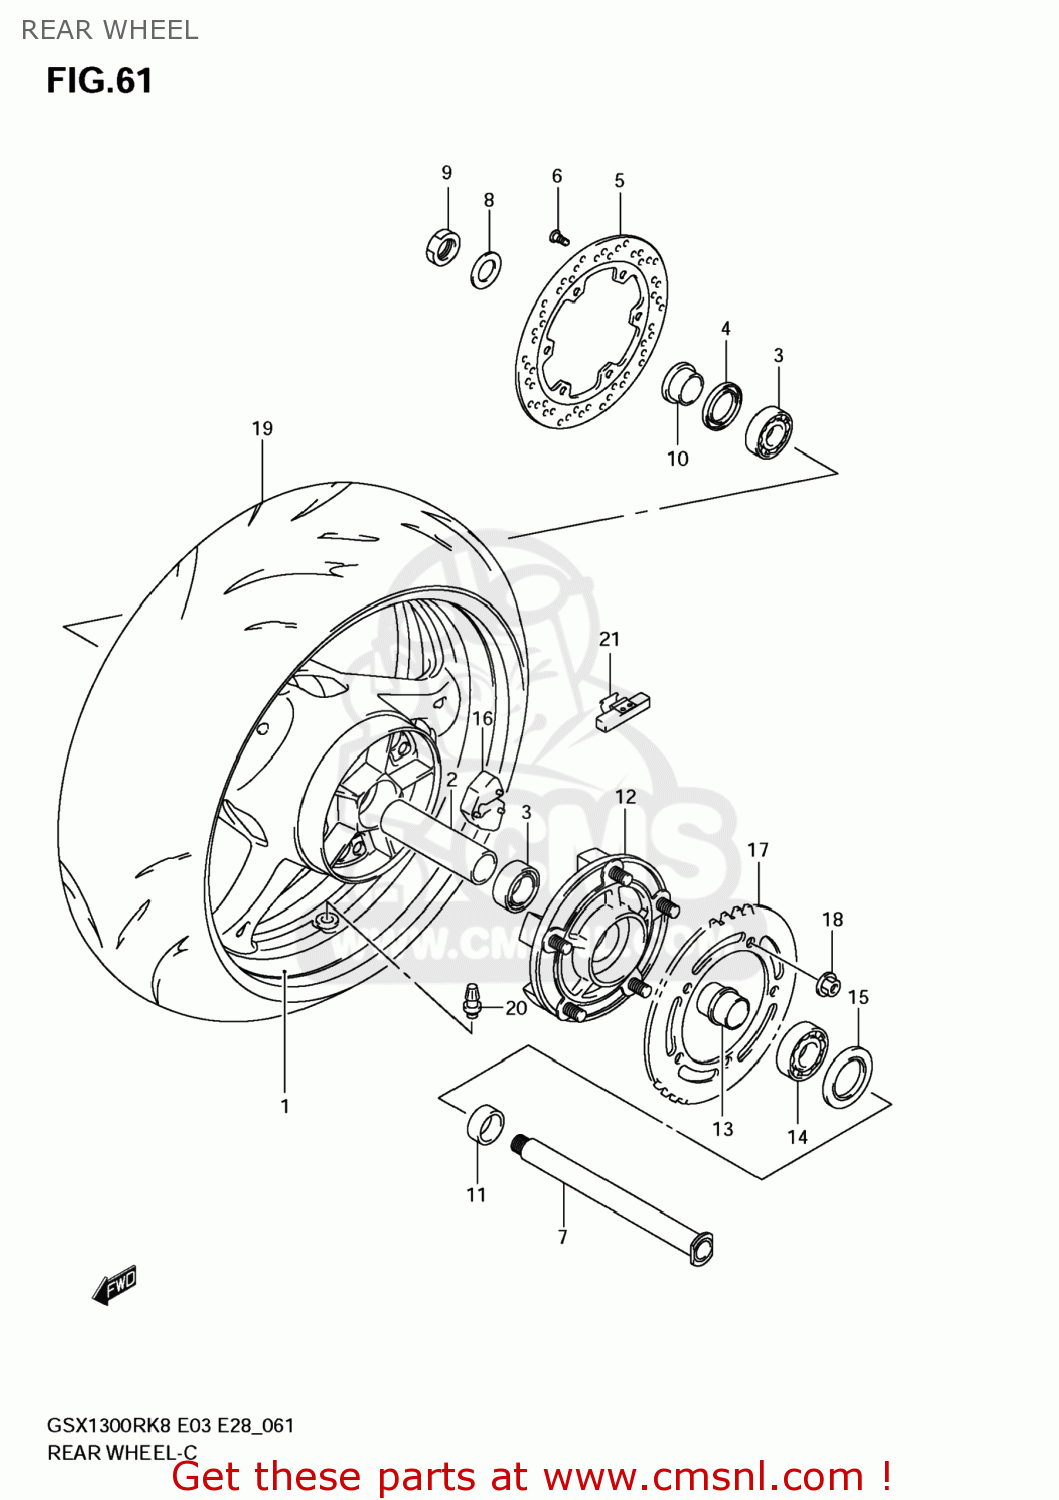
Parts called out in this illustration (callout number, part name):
1	WHEEL,RR(17M/CXMT6.00)
2	SPACER,RR WHEEL BEARING
3	BEARING(28X52X12)
4	SEAL,OIL(37X52X8)
5	DISC,RR BRAKE
6	BOLT(8X21)
7	AXLE,RR
8	WASHER(25.2X42X3.2)
9	NUT
10	SPACER,RR AXLE,R
11	SPACER,RR AXLE,L
12	DRUM,RR SPROCKET
13	RETAINER,RR SPROCKET DRUM
14	BEARING
15	SEAL,OIL(39X65X7)
16	ABSORBER,RR HUB SHOCK
17	SPROCKET,REAR(
18	NUT
19	TIRE,RR
20	VALVE ASSY,WHEEL RIM(TR412)
21	BALANCER,WHEEL(10G)
